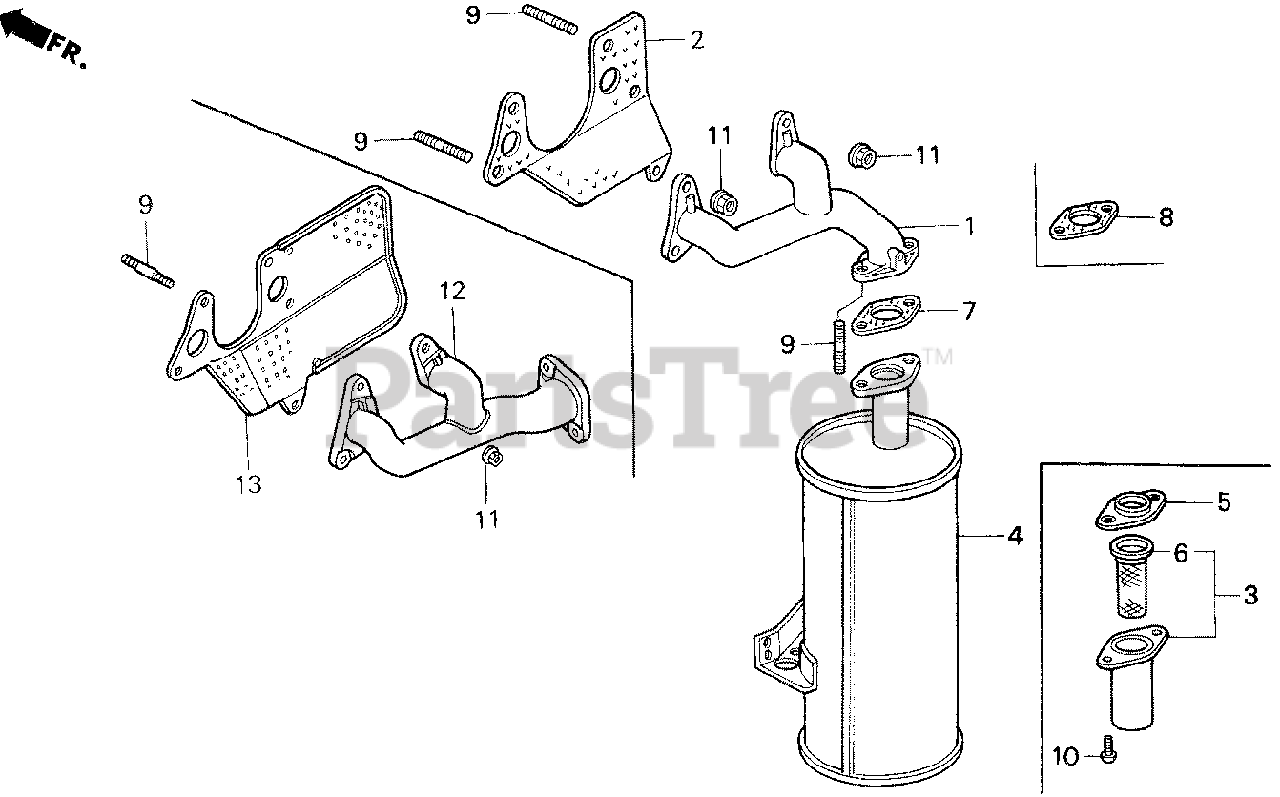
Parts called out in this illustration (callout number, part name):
1	MANIFOLD, EX.
2	GASKET, EX.
3	CAP SET, ARRESTER (Honda Code 1298652). (NOT AVAILABLE)
4	MUFFLER
5	BASE, ARRESTER
6	ARRESTER, SPARK
7	GASKET, MUFFLER
8	GASKET, MUFFLER
9	BOLT, STUD (8X35)
10	SCREW, PAN (5X8)
11	NUT, FLANGE (8MM)
